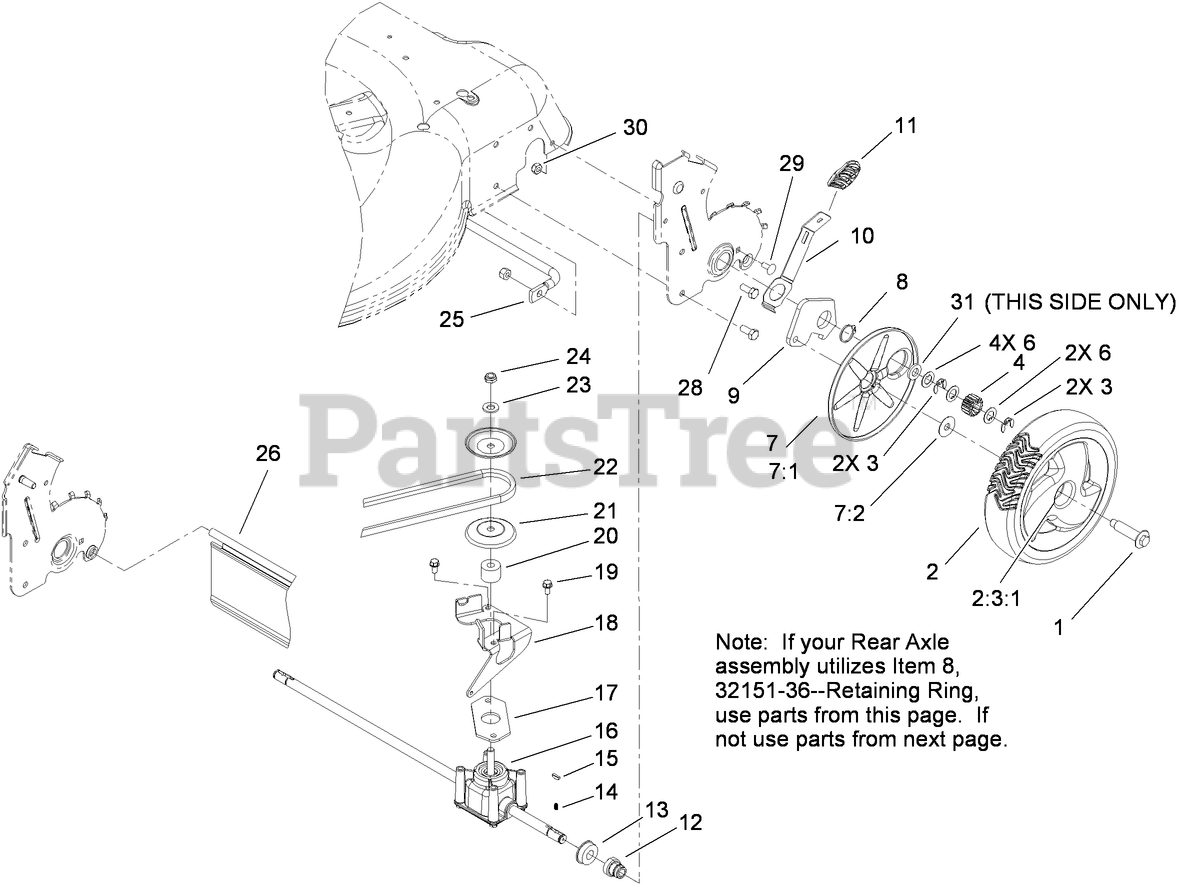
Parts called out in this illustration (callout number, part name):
1	BOLT-SHOULDER
2	WHEEL GEAR ASM
2:3	Loose Parts Package
2:3:1	BUSHING
3	RING-RETAINING,CLIP
4	GEAR-PINION, 15T
6	WASHER-THRUST
7:1	Loose Parts Package
7:2	WASHER-STEPPED
8	RING-RETAINING
9	ARM-PIVOT, REAR (LH)
10	ARM-SPRING
11	KNOB-LEVER, HOC
12	RETAINER-BEARING, HOC
13	BEARING-BALL
14	SPRING-COMPRESSION
16	TRANSMISSION ASM
17	GASKET-GEARBOX
18	BRACKET-PIVOT
19	SCREW-HWH
20	SPACER
21	PULLEY-HALF
22	BELT-V
23	WASHER-FLAT
24	NUT-HEX
25	BRACE-PLATE, HOC
26	SHIELD-TRAILING
28	SCREW-HH
29	SCREW-CARR
30	NUT-LOCK, NI
31	WASHER-PLAIN
